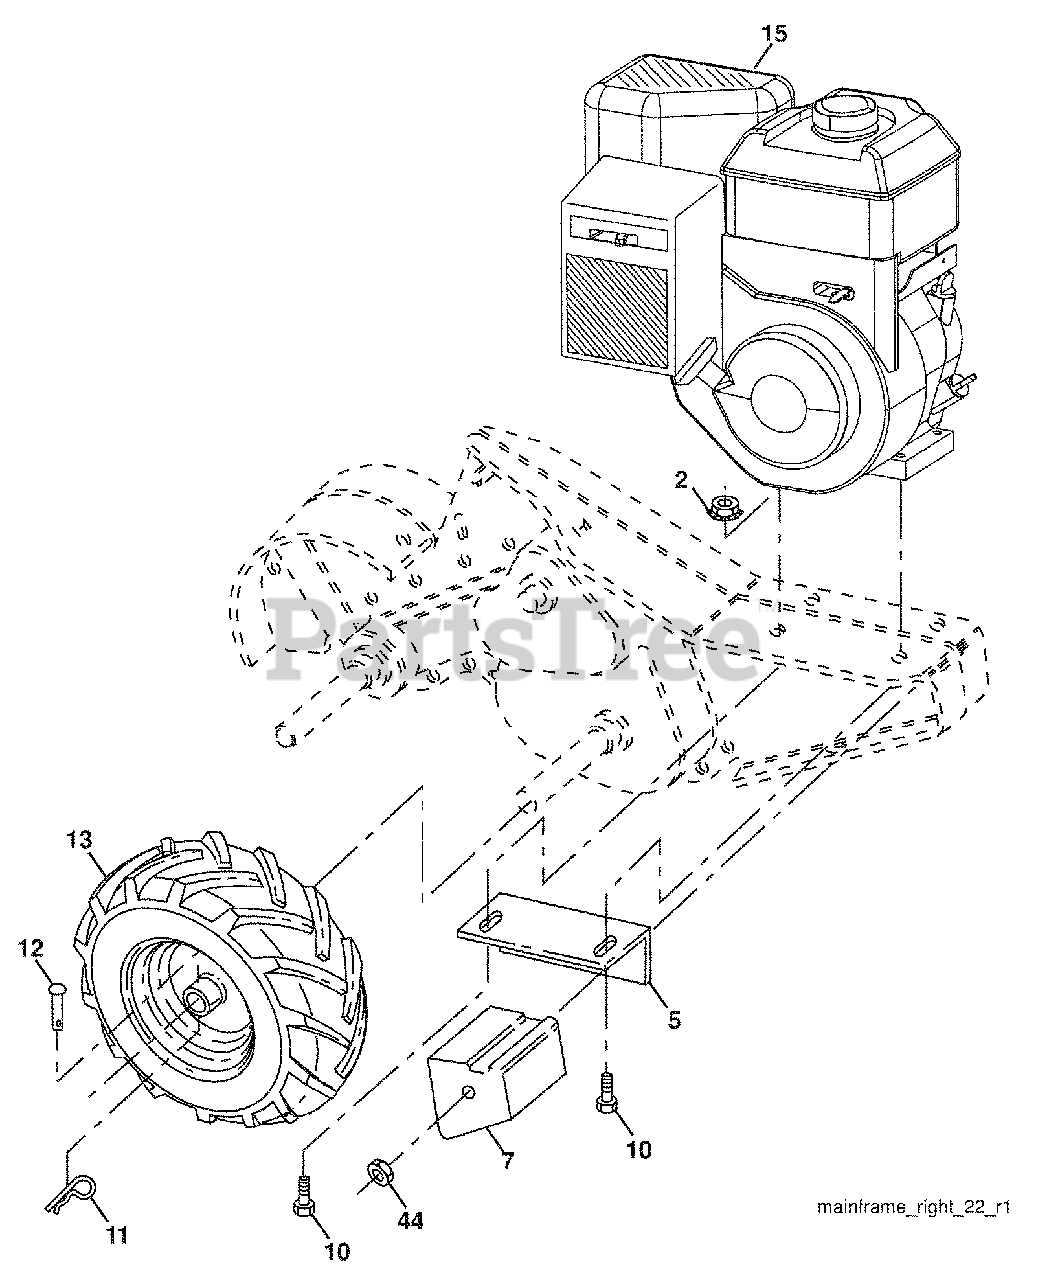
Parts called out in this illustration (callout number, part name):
2	Locknut, Hex, Flange 5/16-18
5	Bracket, Reinforcement RH
7	Counter Weight, R.H.
10	Bolt, Hex 5/16-18 x 1-1/2
11	Clip, Hairpin
12	Rivet, Drilled
44	Nut, Keps Hex 3/8-16 unc
